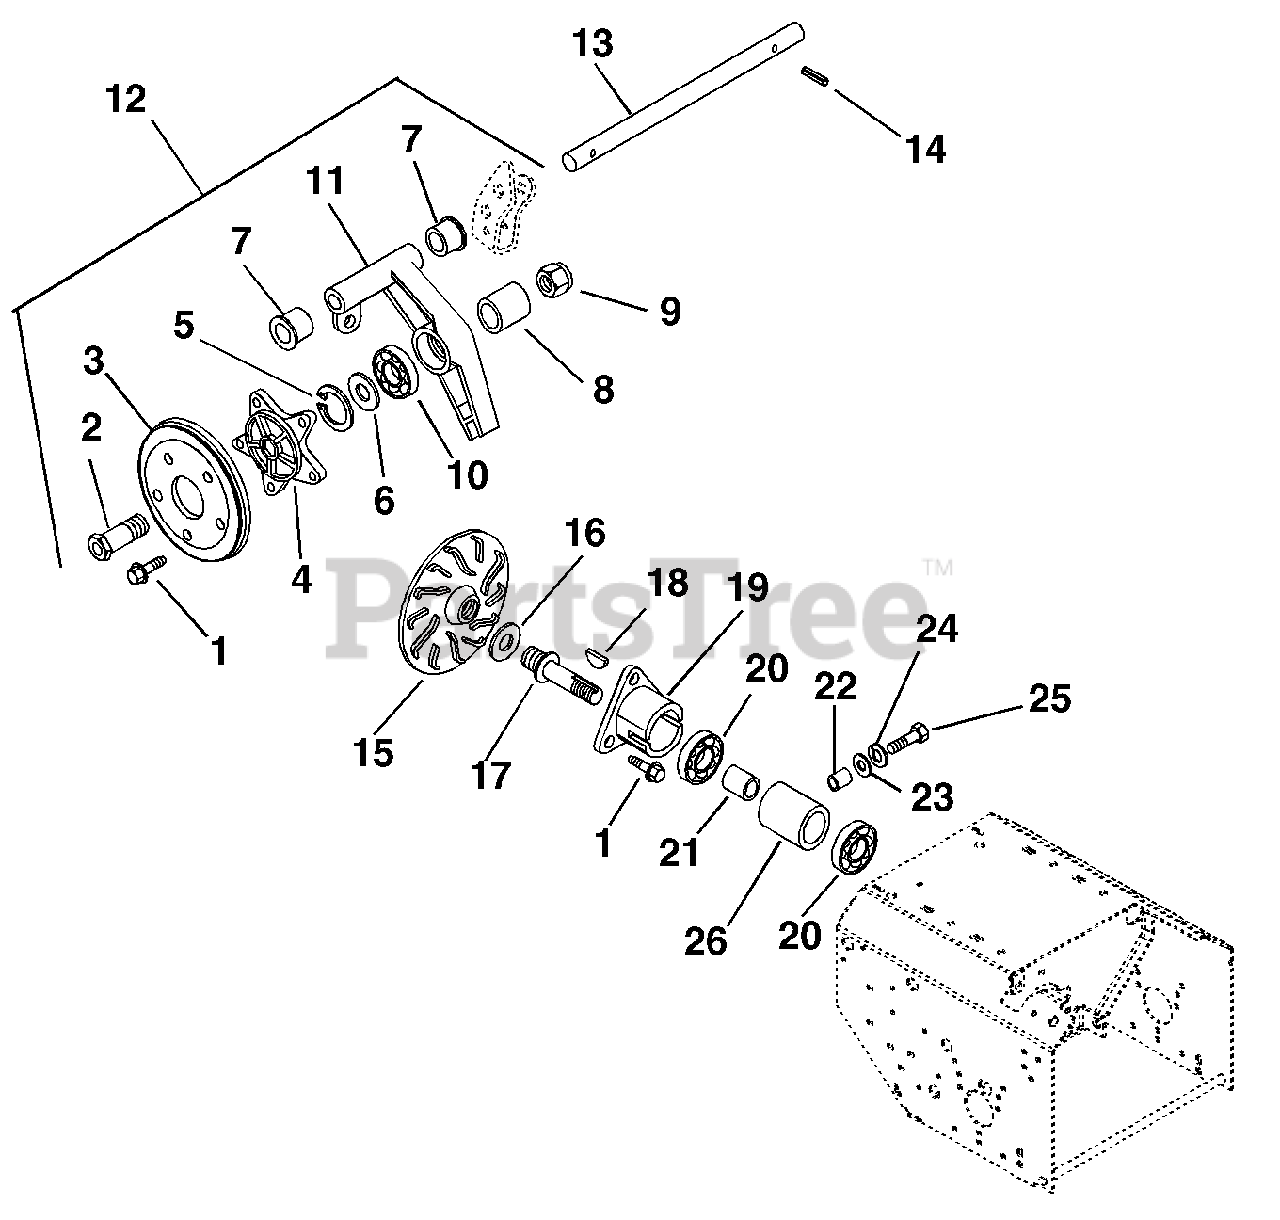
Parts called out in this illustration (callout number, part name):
1	@SCR-TAP .31-18X.50 HWH TR YWZ
2	SPINDLE HUB
3	FRICTION DISC
4	DISC HUB
5	RG-RTNG-INT 1.750X.062
6	WSHR-FL-STL .880X1.250X.062YWZ
7	BSHG-FLG .625X.750X.500X.875BR
8	BSHG-SLV .882X1.250X.531
9	NUT-LK-NYL .875-14 YWZC
10	BRG-BALL .876 X 1.750 X .50
11	CARRIER
12	FRICTION WHEEL ASSEMBLY
13	SHAFT, CARRIER
14	PIN-ROLL .156X1.00
15	DRIVE PLATE
16	DRIVE DISC SPACER 1.3X.76X.19
17	SPINDLE
18	KEY-WDRF .125X.500X.203 SAE 3
19	HOUSING MOUNT
20	BRG-BALL .625X1.375X.43
21	BEARING SPACER
23	@WSHR-FL-STL.344X.688X.065YWZC
24	@WSHR-LK .31X.078 REG YWZC
25	@BLT-HEX .31-18X1.00 GR5 YWZC
26	SPINDLE HOUSING
